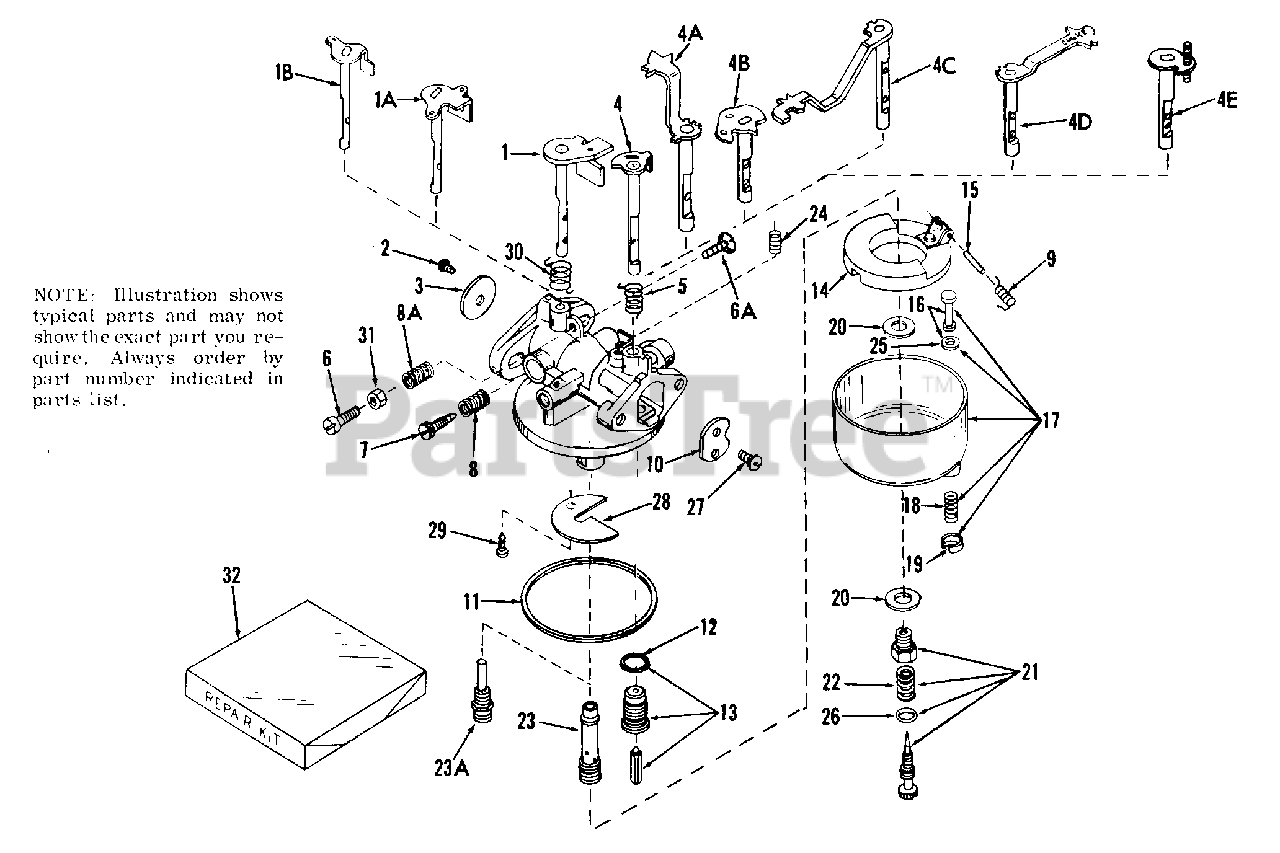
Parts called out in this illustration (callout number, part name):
1	"Shaft & Lever Assy., Throttle
2	Screw, Sems, 6-32 x 3/16
3	Shutter, Throttle
4A	Shaft & Lever Assy., Choke
6	Screw, Throttle adjusting
7	Needle, Idle adjusting
8	Spring, Adjusting needle
8A	Spring, Adjusting needle
10	Shutter, Choke
11	Gasket, Bowl-to-body
12	Gasket, Valve seat
13	Valve, Seat & Gasket Assy.
15	Shaft, Float
16	Stem Assy., Bowl drain
17	Bowl & Drain Assy.
18	Spring, Bowl drain
19	Retainer, Bowl drain stem
20	Gasket, Bowl-to-body
21	Needle Assy., Power adjusting
22	Spring, Power needle
23	Nozzle, Main
25	Gasket, Drain stem
26	"O" Ring
27	Screw, Sems
28	Baffle, Carburetor
29	Screw, Baffle
30	Spring, Throttle return
32	Repair Kit
